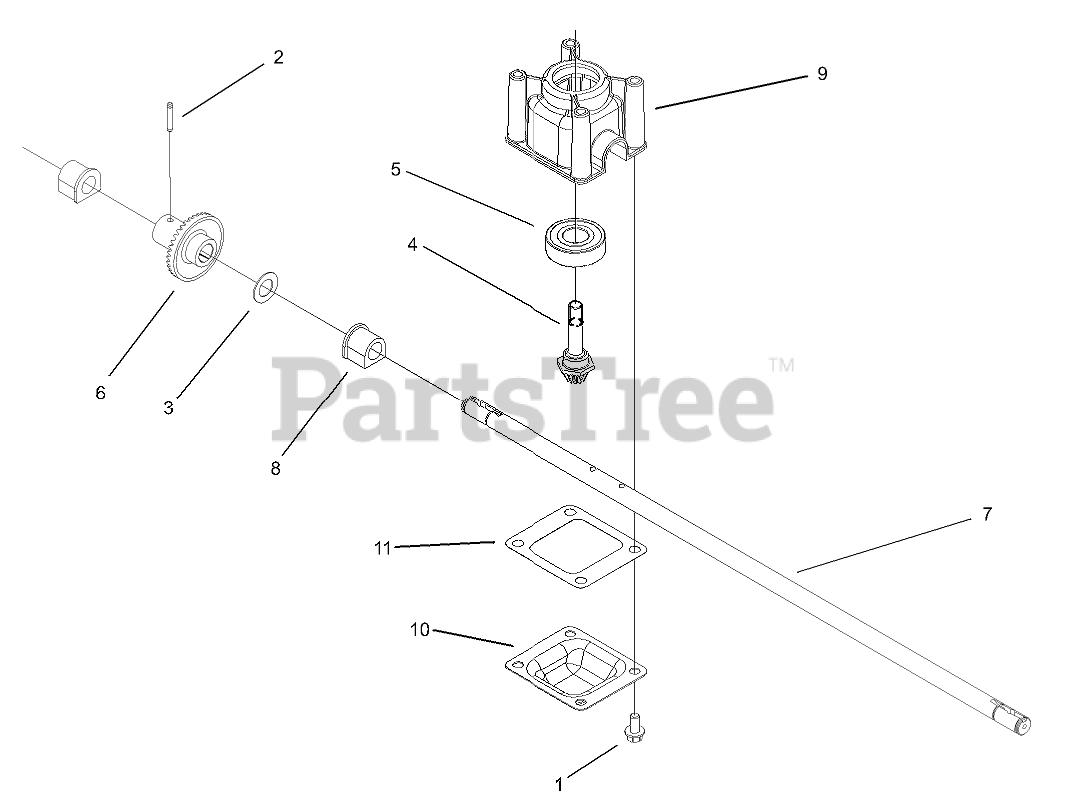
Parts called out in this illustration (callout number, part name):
1	SCREW-HWH
2	Pin-Groove
3	WASHER-PLAIN
4	PINION
5	BEARING-BALL
6	Gear-Bevel, 37t
7	Shaft-Output
8	Bushing-Shaft, Output
9	Gearcase-Upper
10	Cover-Gearcase
11	Gasket-Gearcase
